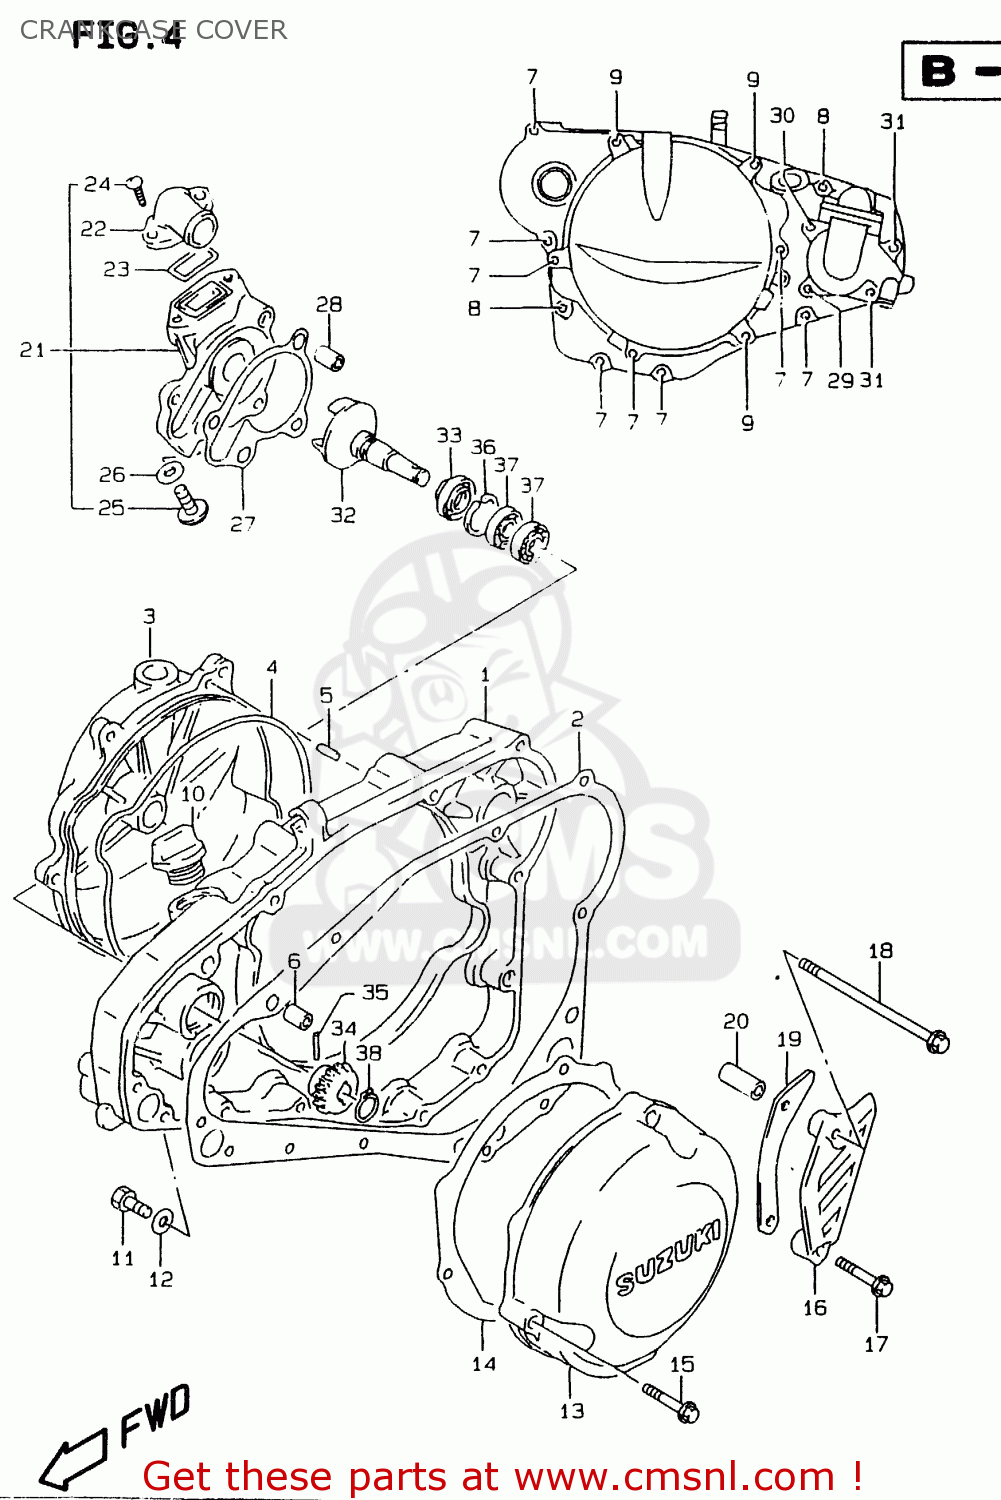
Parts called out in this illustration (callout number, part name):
1	COVER,CLUTCH
2	GASKET,CLUTCH COVER (NAS)
3	COVER,CLUTCH OUTER
4	O RING,CLUTCH COVER OUTER
5	PIN
6	PIN
7	SCREW
8	BOLT
9	BOLT
10	PLUG SET
11	SCREW(6X10)
12	GASKET(6.2X11X1).2 (NAS)
13	COVER,MAGNETO
14	GASKET,MAGNETO COVER (NAS)
15	SCREW
16	COVER,ENGINE SPROCKET
17	SCREW
18	BOLT
19	PLATE,FR CHAIN GUIDE(13T)
20	SPACER(6.5X10.5X25)
21	CASE ASSY,WATER PUMP
22	CONNECTOR
23	O RING,WATER PUMP CONNECTOR
24	SCREW
25	BOLT
26	WASHER
27	GASKET,WATER PUMP CASE (NAS)
28	PIN
29	SCREW
30	BOLT,G/S SWITC
31	BOLT
32	IMPELLER,WATER PUMP
33	SEAL,WATER PUMP OIL
34	GEAR,WATER PUMP DRIVEN(NT:24)
35	PIN(3X13.8)
36	CIRCLIP
37	BEARING
38	CIRCLIP,10MM
